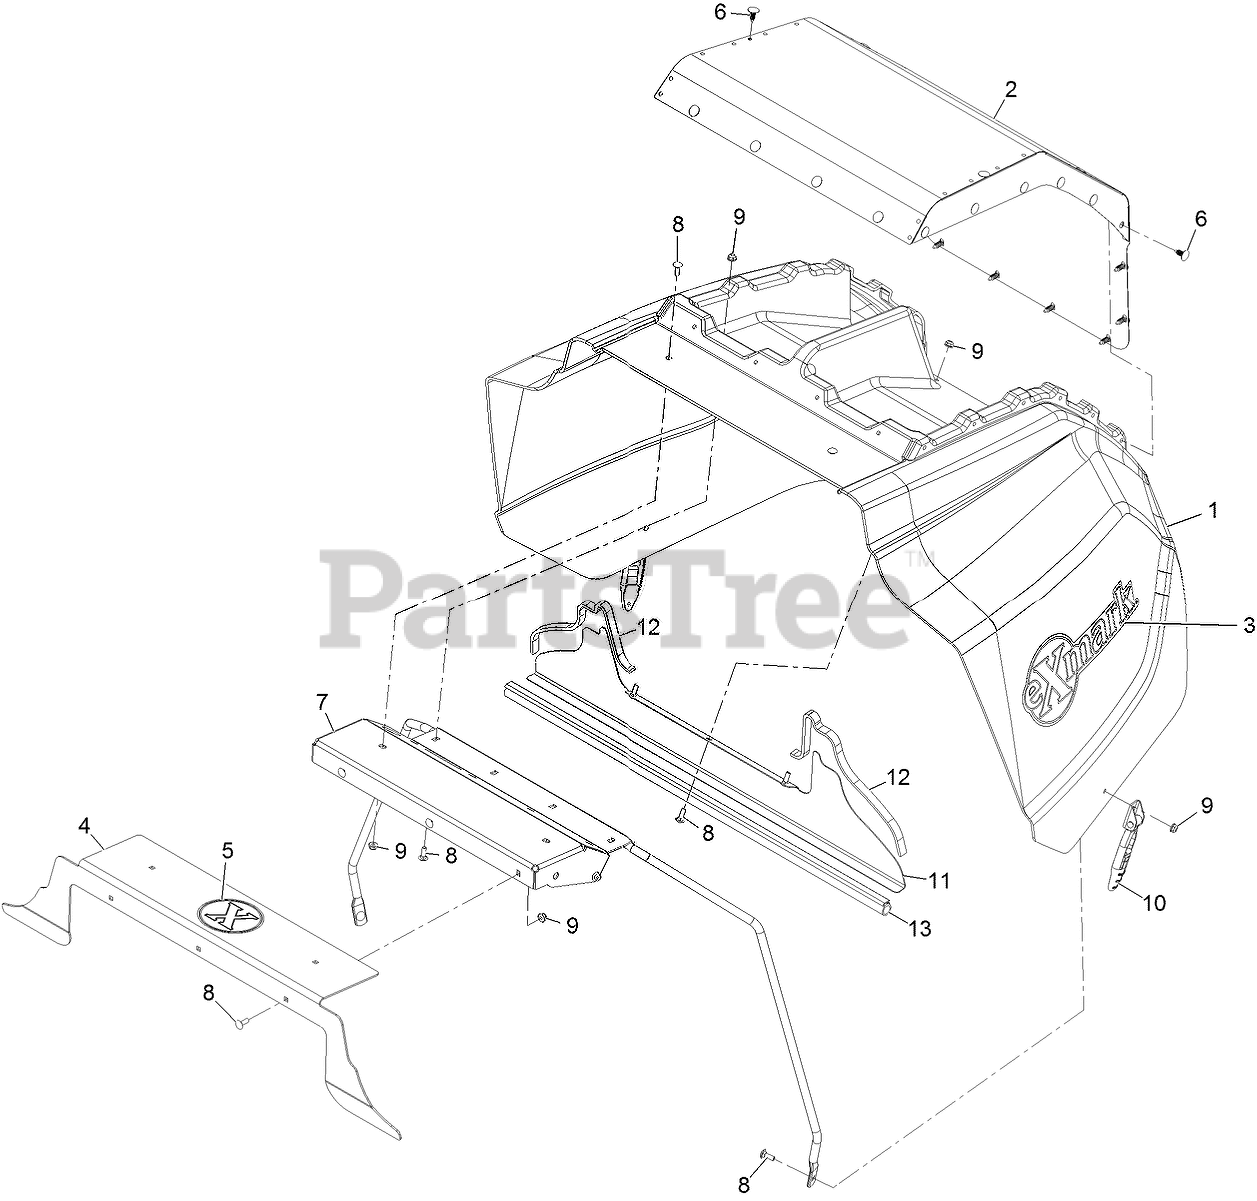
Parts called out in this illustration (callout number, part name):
1	HOOD,LZSD
2	Screen-Intake
3	DECAL-EXMARK
4	Block Off-Hood
5	DECAL-X-LOGO
6	PLUG-PLASTIC
7	SUPPORT-HOOD
8	BOLT-CARR
10	LATCH-RUBBER
11	Plate-Seal
12	SEAL-FOAM
13	Seal-Bulb
